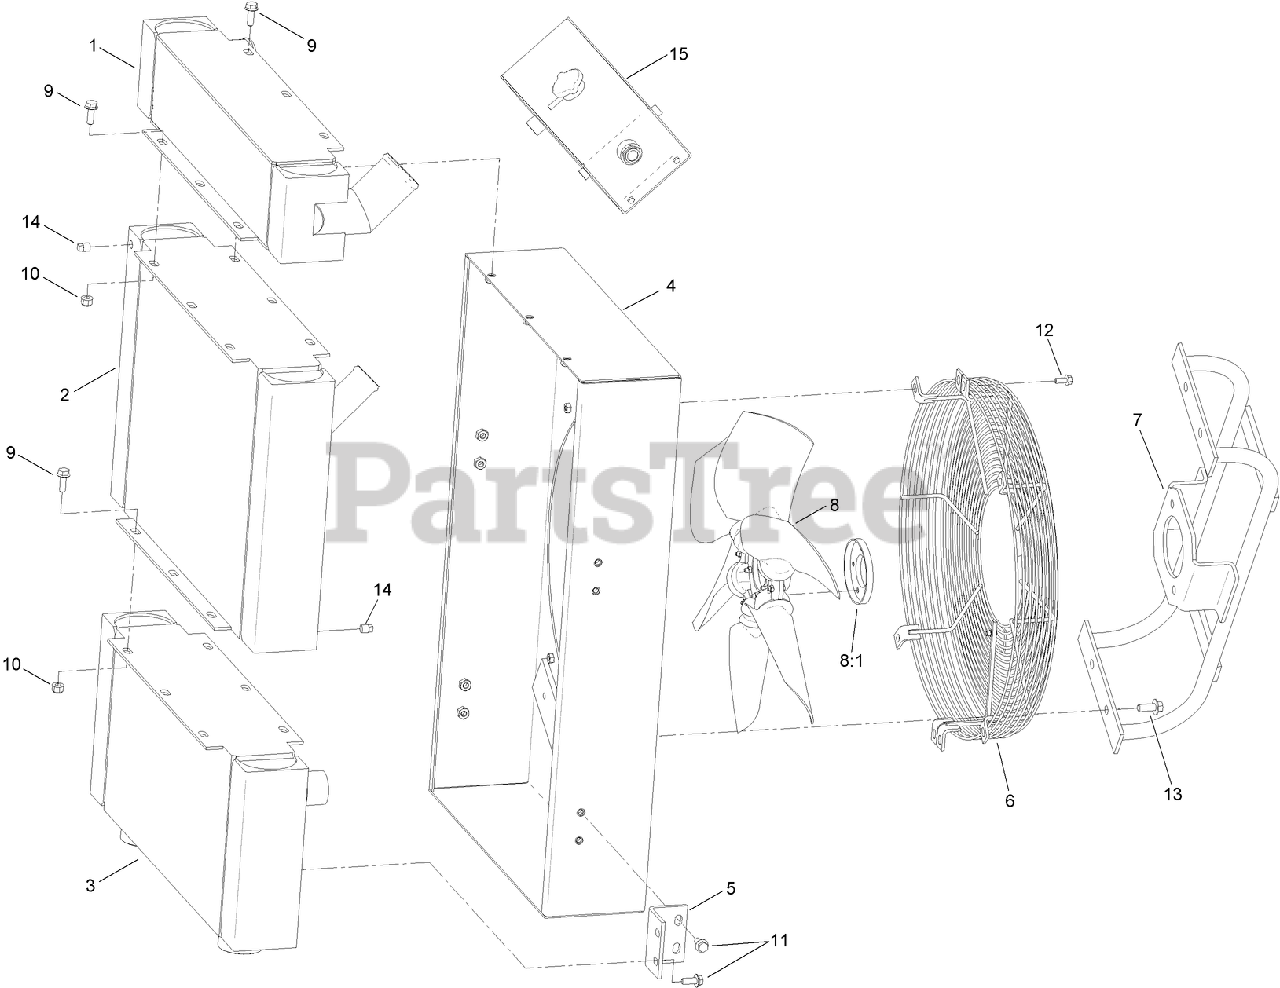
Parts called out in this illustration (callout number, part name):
1	COOLER-AIR, CHARGE
2	COOLER-RADIATOR
3	COOLER-OIL
4	SHROUD-FAN
5	PLATE-MOUNTING, SHROUD
6	GUARD-FAN, 22 INCH
7	BRACKET-MOUNTING
8	OBS FAN-COOLING, 22IN
8:1	SPACER-FAN
9	SCREW-HHF
10	NUT-LOCK, NI
11	SCREW-HHF
12	SCREW-HHF
13	SCREW-HHF
14	PLUG-PIPE, SQH
15	TANK-FILL/SURGE
